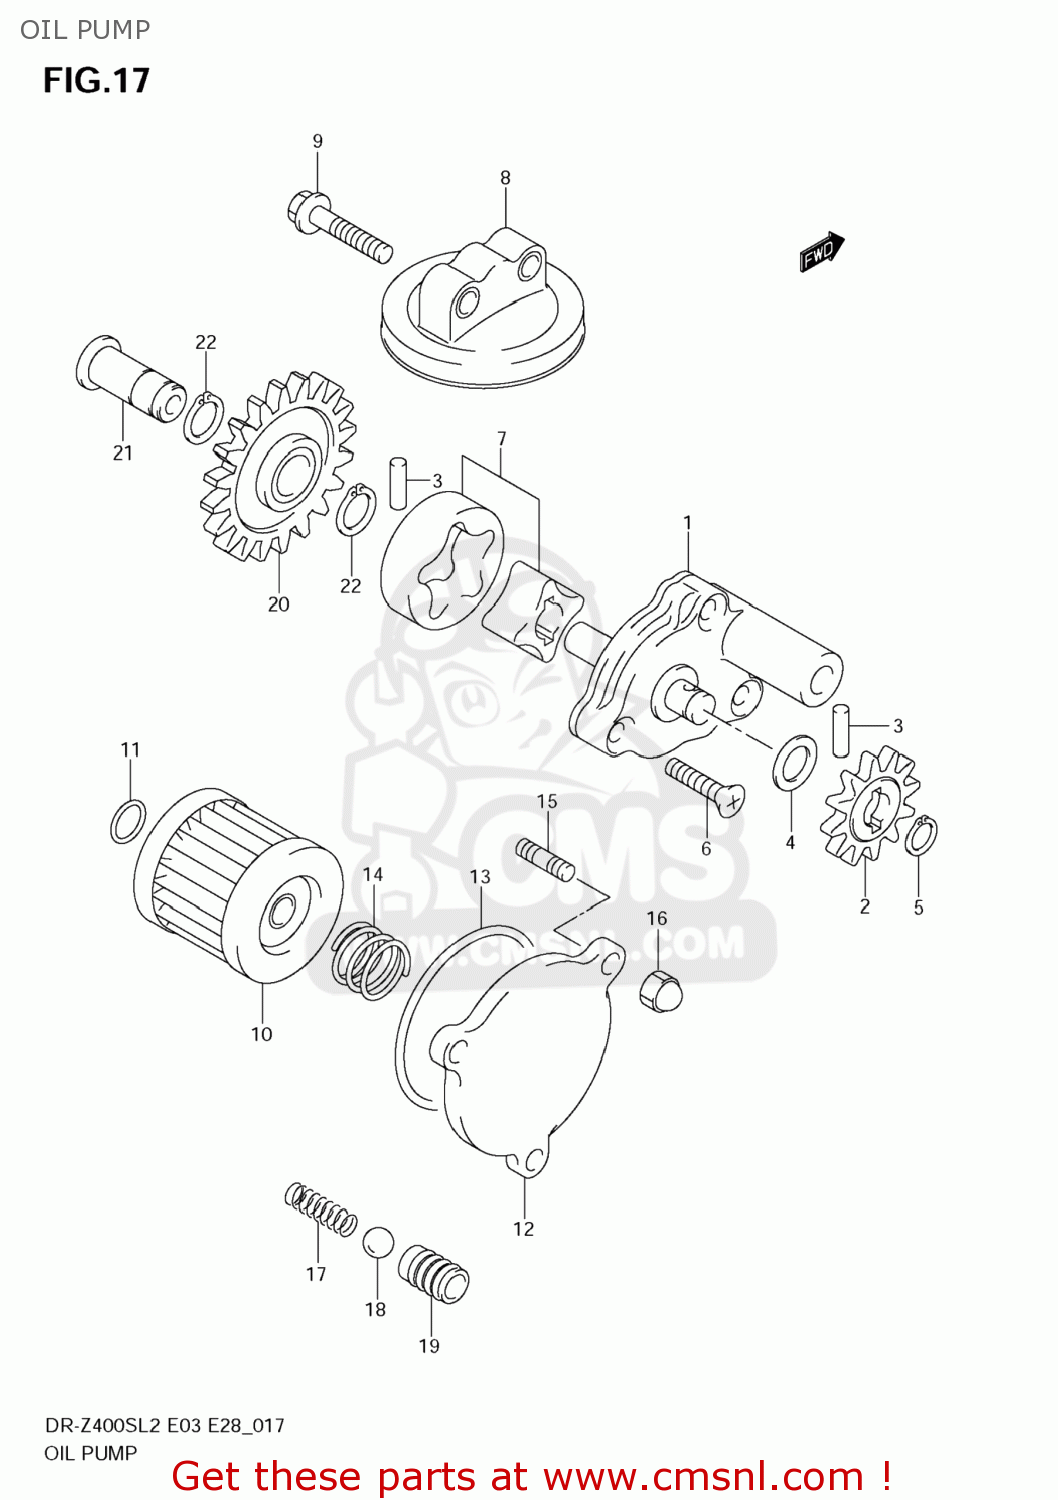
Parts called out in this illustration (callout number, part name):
1	PUMP ASSY,ENGINE OIL NO.1
2	GEAR,OIL PUMP DRIVEN
3	PIN(4X15.8)
4	SHIM(10X18X0.5)
5	CIRCLIP
6	SCREW
7	ROTOR SET,OIL PUMP,NO.2
8	STRAINER,OIL PUMP NO.2
9	BOLT
10	FILTER ASSY,ENGINE OIL
11	O RING(D:1.9,ID:13)
12	CAP,OIL FILTER
13	O RING(D:2.4,ID:52.6)
14	SPRING
15	BOLT,STUD
16	NUT
17	SPRING
18	BALL
19	SEAT,OIL CHECK VALVE
20	GEAR,OIL PUMP IDLE
21	SHAFT,OIL PUMP IDLE GEAR
22	CIRCLIP
